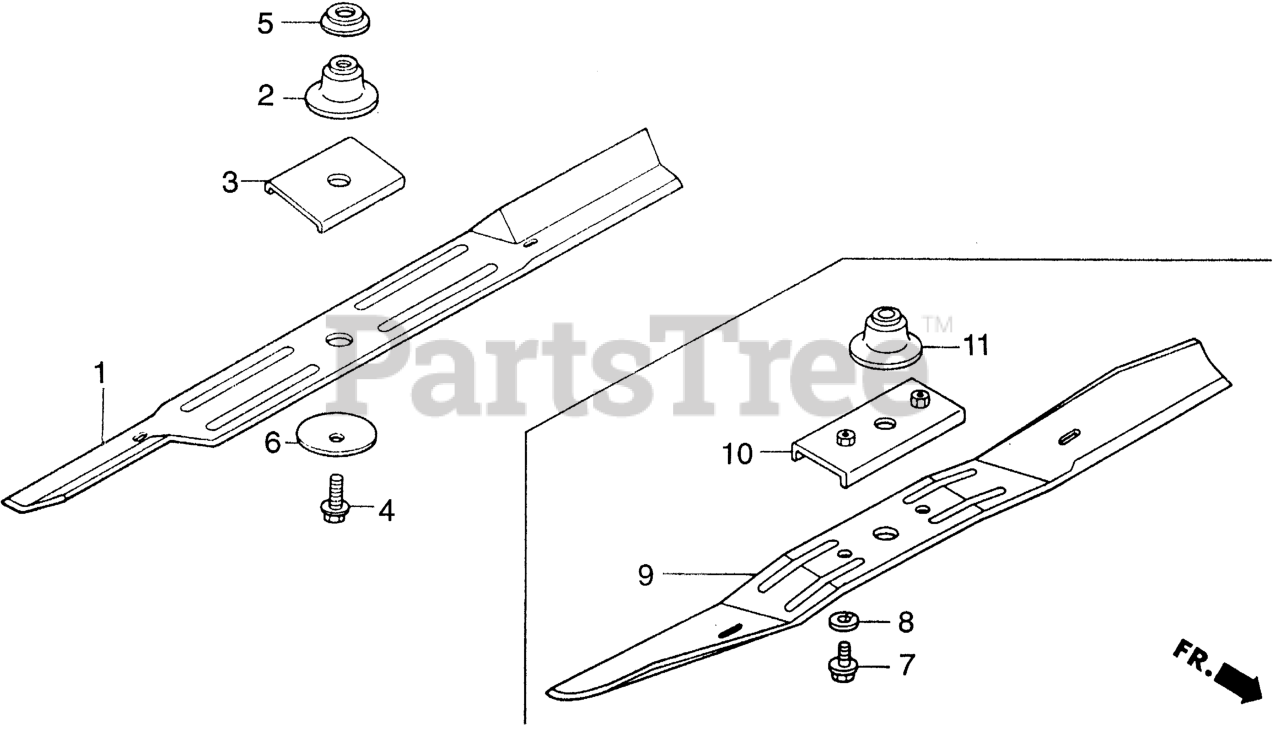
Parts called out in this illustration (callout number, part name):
1	BLADE, ROTARY
2	HOLDER, BLADE
3	HOLDER, BLADE (B)
4	BOLT, BLADE HOLDER (10X28)
5	WASHER, BLADE HOLDER
6	WASHER, BLADE
7	BOLT, FLANGE (12X25)
8	WASHER, SPRING (12MM)
9	BLADE, ROTARY
10	HOLDER, BLADE
11	HOLDER, BLADE
